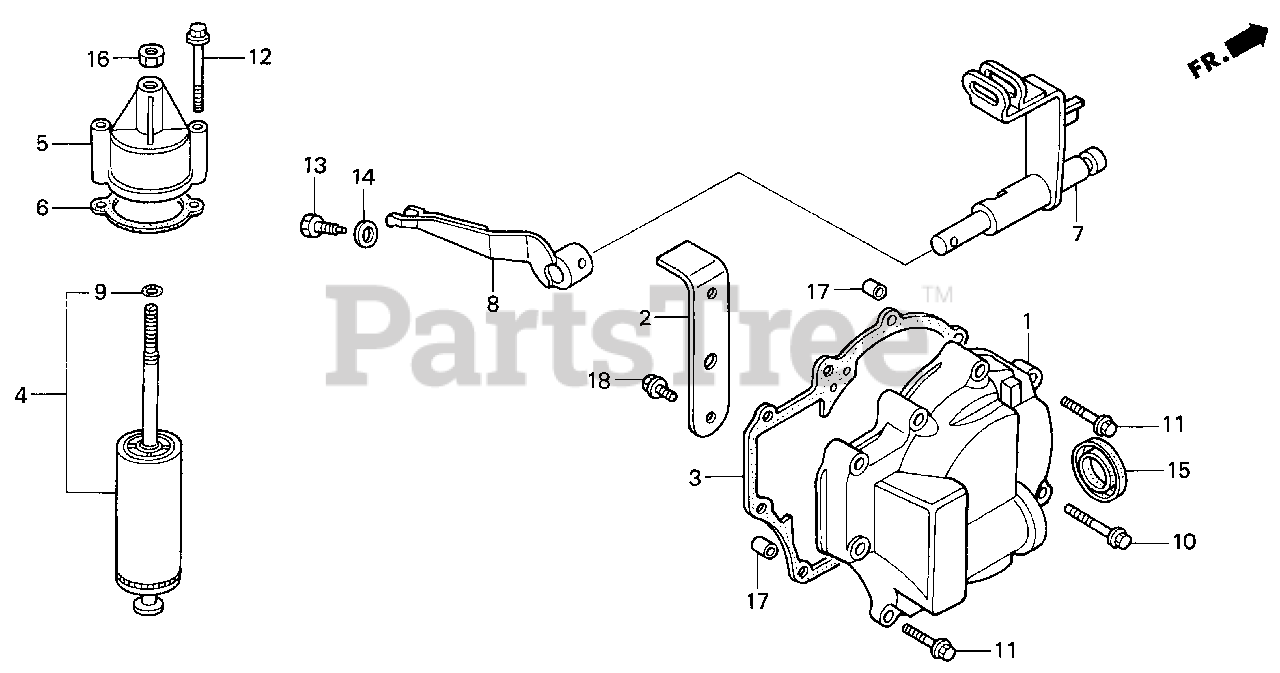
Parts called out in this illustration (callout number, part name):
1	COVER, CLUTCH
2	GUIDE, OIL
3	GASKET, CLUTCH COVER
4	DAMPER ASSY., CLUTCH
5	BRACKET, DAMPER (UPPER)
6	GASKET, CLUTCH DAMPER
7	SHAFT, CLUTCH
8	ARM, DAMPER
9	O-RING A (7.5X1.5)
10	BOLT, FLANGE (6X40) (CT200)
11	BOLT, FLANGE (6X35)
12	BOLT, FLANGE (6X50)
13	BOLT, SPECIAL (8X24)
14	WASHER, CONICAL SPRING (8MM)
15	OIL SEAL (26X34.5X5.5)
16	NUT, HEX. (8MM)
17	PIN A, DOWEL (8X14)
18	BOLT, FLANGE (6X12)
